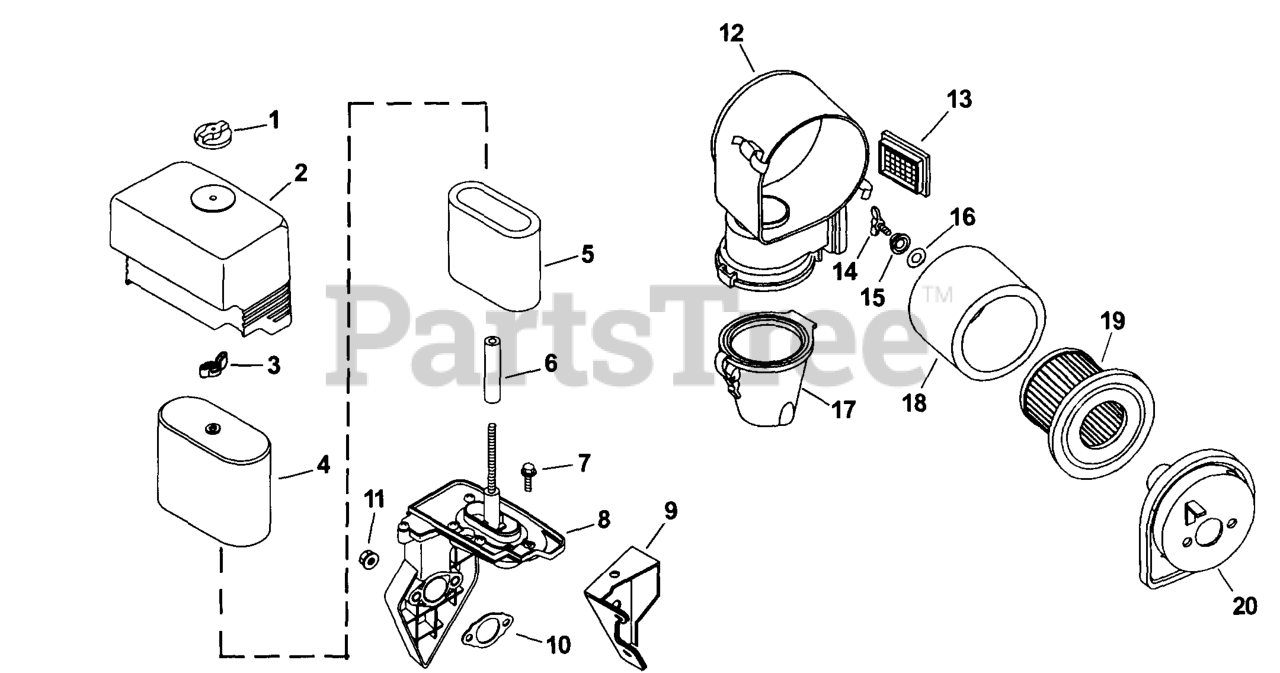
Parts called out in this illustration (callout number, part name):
1	KNOB,AIR CLEANER
2	COVER, AC
3	NUT, WING - DISCONTINUED
4	ELEMENT, PAPER
5	PRECLEANER, ELEMENT
6	SEAL, A/C
8	BASE, A/C
9	BRACKET, A/C
10	GASKET, A/C
11	NUT A/C H-D
